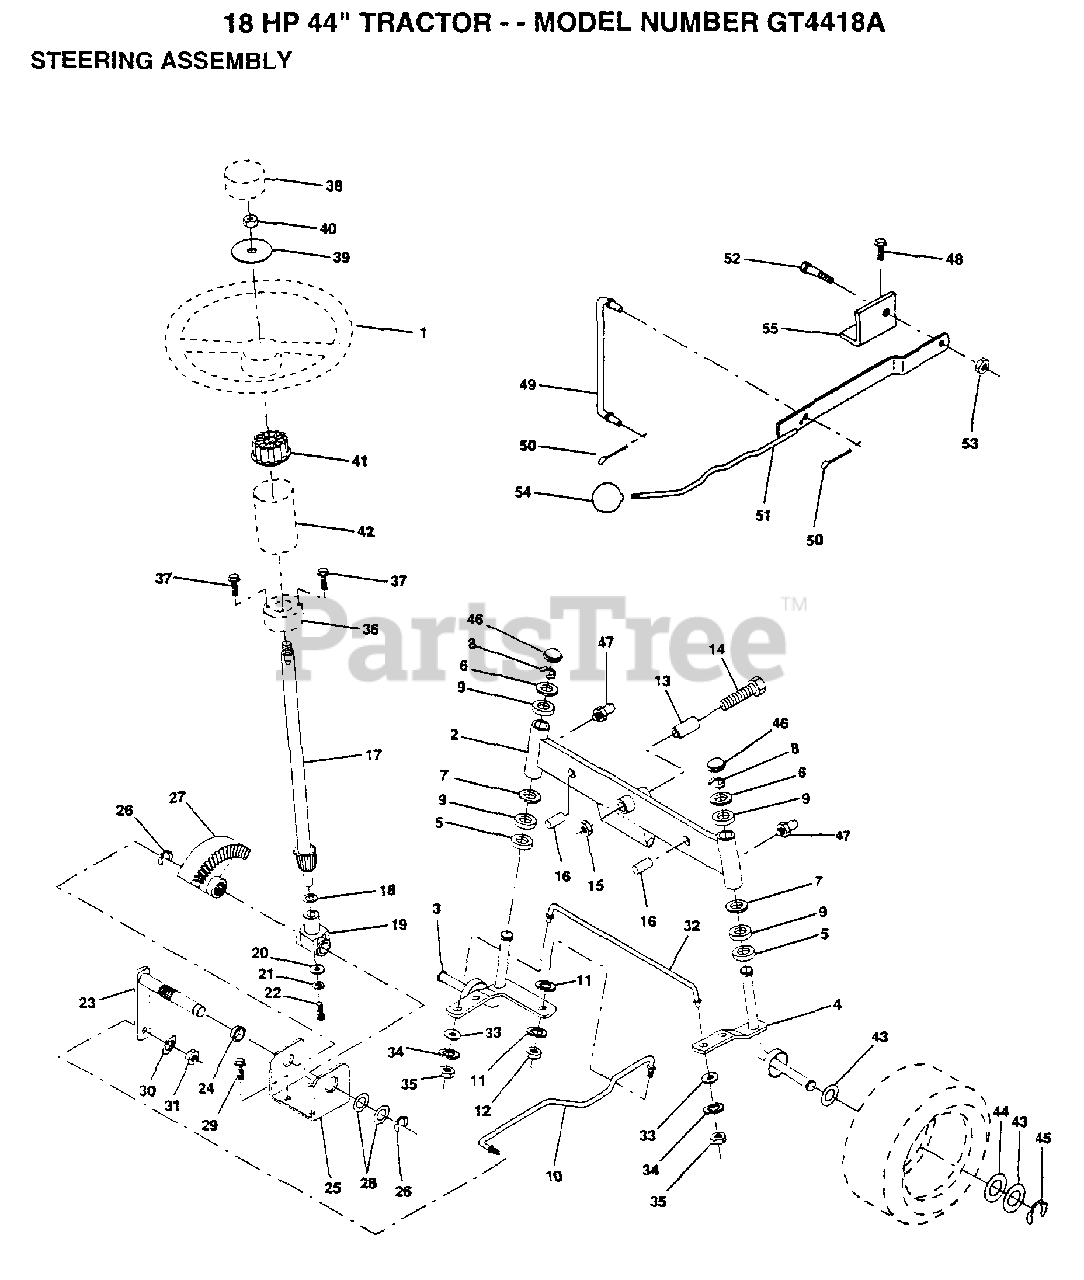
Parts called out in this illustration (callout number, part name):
2	AXLE ASM FRONT
5	WASHER .T
6	WASHER
7	WASHER
8	RING
9	COL. SRTG. BEAR.
11	LOCKWASHER
13	BEARING
14	BOLT LT
15	"NUT-LOC,FLANGE LT"
16	AXLE PIN
17	SHAFT&GEAR STR T
18	THRUST WASHER
19	SUPPORT.SHAFT
21	LOCKWASHER
22	"SCREW,SPECIAL"
24	NYLINER T
25	"BRKT,STEERING"
26	RING
27	GEAR SECTOR
28	WASHER .T
29	SCREW
30	LOCKWASHER
32	ROD.TIE.19.75
33	WASHER M
34	LOCKWASHER
35	NUT.LOCK.5/16-24
38	ST WHL INSERT CAP
39	WASHER
41	ADAPTER LT
43	WASHER
44	WASHER
45	RING
46	CAP
47	ZERK M
48	SCREW
49	LINK CLTCH W/NUTS
50	COTTER PIN
51	LEVER ASSY T
52	"BOLT, SHOULDER LT"
54	KNOB T (1/2-HOLE)
55	BRKT.PVT.MAN.LVR.
